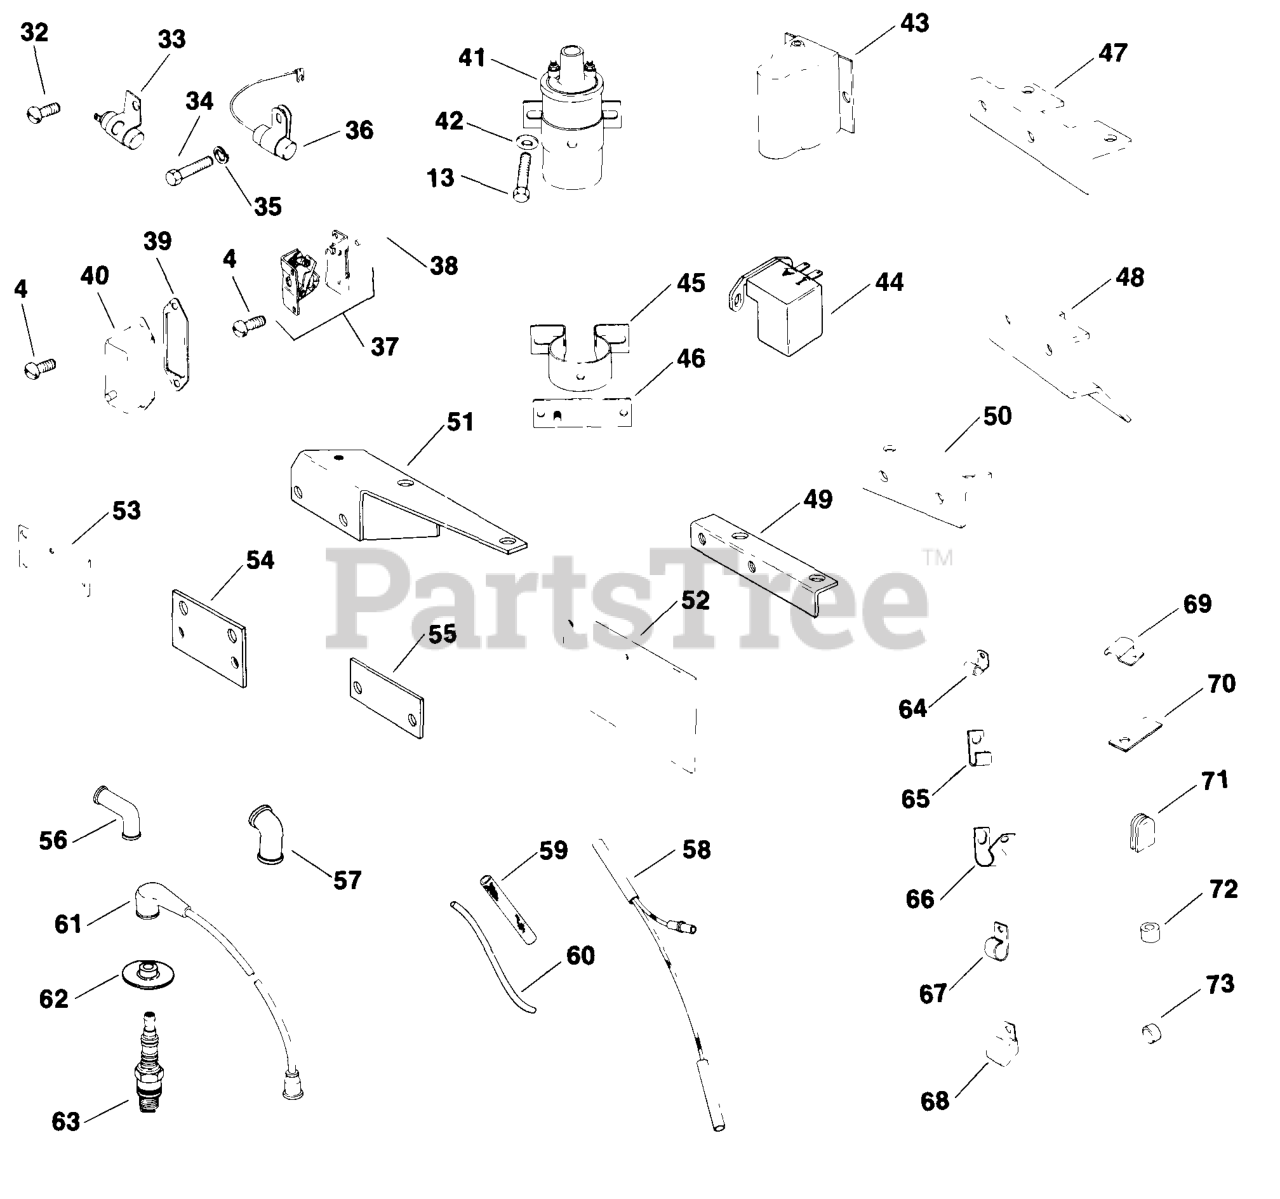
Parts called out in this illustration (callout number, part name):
36	CONDENSER
37	BREAKER
39	GASKET, POINT COVER
40	COVER - DISCONTINUED
41	COIL, IGNITION USE 41 519 21-S
61	KIT, HI-TENSION-(#DSC)
63	SPARK PLUG - USE Champion RJ8C
71	GROMMET
